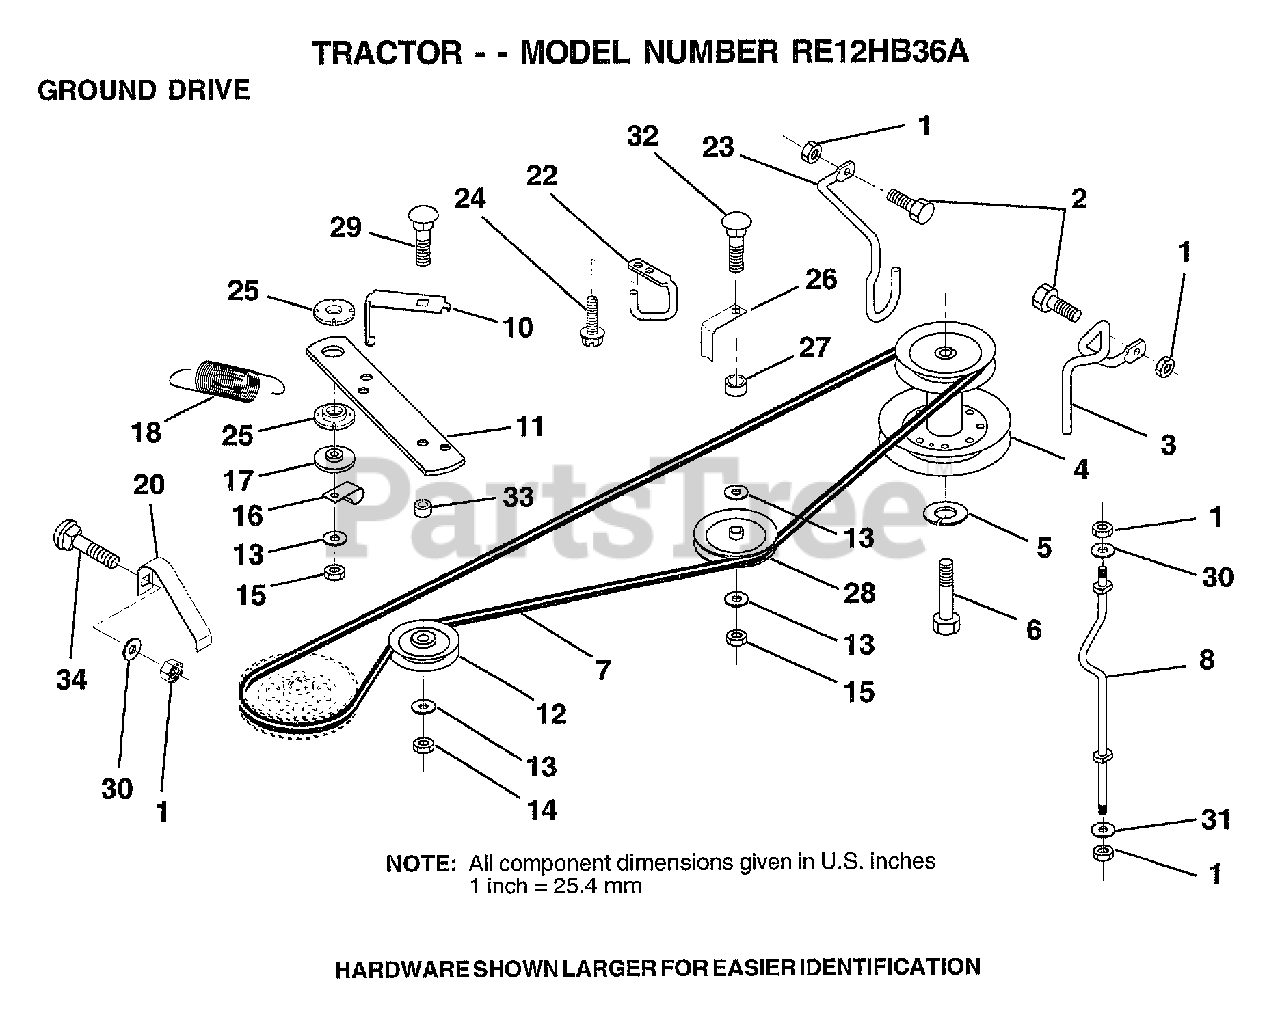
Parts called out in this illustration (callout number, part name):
1	NUT
2	BOLT
3	KEEPER.BELT.FRT.
4	PULLEY.ENGINE.LR
5	LOCKWASHER
6	HEX BOLT
7	BELT-V.DRV.77.75
8	KEEPER.BELT.HYDRO
10	KEEPER.BELT.GRD.
11	ARM-IDLER.DR.GRND
12	PULLEY.IDLER.FLAT
13	WASHER
14	LOCKNUT
16	"CLIP,INSULATOR"
17	SPACER
20	KEEPER.BELT.LH
22	"KEEPER,FRA DR BEL"
23	KEEPER MOWER LH
24	SCREW
25	BUSHING.NYLON
26	KEEPER.BELT.IDLER
27	SPACER.625X.843
28	PULLEY.IDLER.V.GR
29	BOLT RDHD 3/8-16
30	WASHER
31	WASHER M
32	BOLT
34	BOLT
